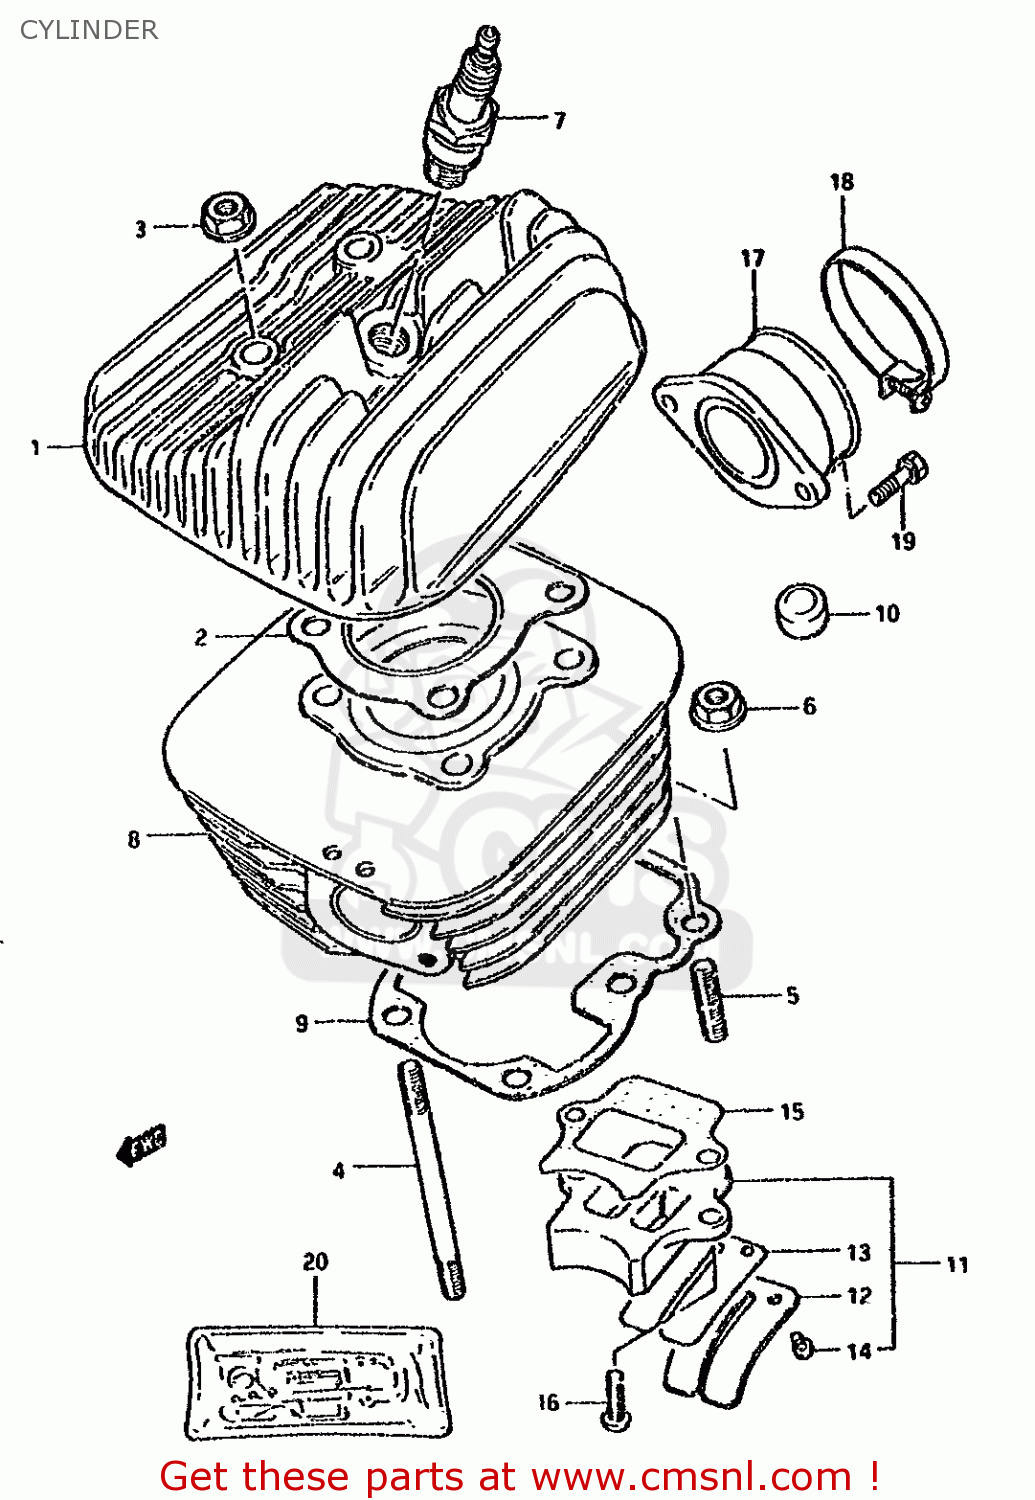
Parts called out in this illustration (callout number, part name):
1	HEAD,CYLINDER
2	GASKET,CYLINDER HEAD (NAS)
3	NUT
4	BOLT,STUD
5	STUD 6X20
6	NUT
7	SPARK PLUG B7ES
8	CYLINDER
9	GASKET,CYLINDER (NAS)
10	PAD,CYLINDER
11	VALVE ASSY,REED
12	STOPPER,REED VALVE
13	VALVE,REED
14	SCREW
15	GASKET,REED VALVE (MCA)
16	SCREW
17	PIPE,INTAKE
18	CLAMP
19	BOLT
20	GASKET SET (NAS)
